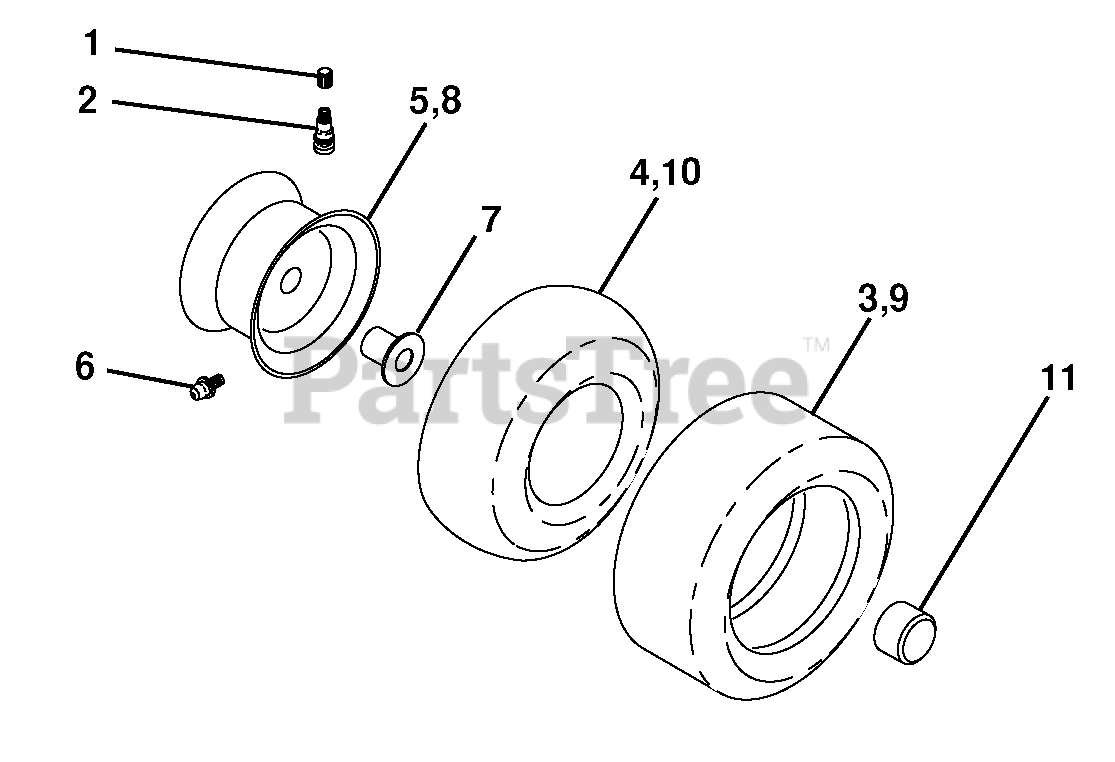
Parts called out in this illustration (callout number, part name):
1	Cap Valve Tire
2	Stem Valve
3	Tire F T 15 x 6 0 - 6 Service
4	Tube Front
5	Rim Asm 6" front Service
6	Fitting Grease
7	Bearing Flange
8	Rim Asm 8" rear Service
9	Tire R T 18 x 9.5-8C Service
10	Tube Rear
11	Cap Axle Blk 1 50 x 1 00
11	Sealant, Tire (10 oz. Tube)
